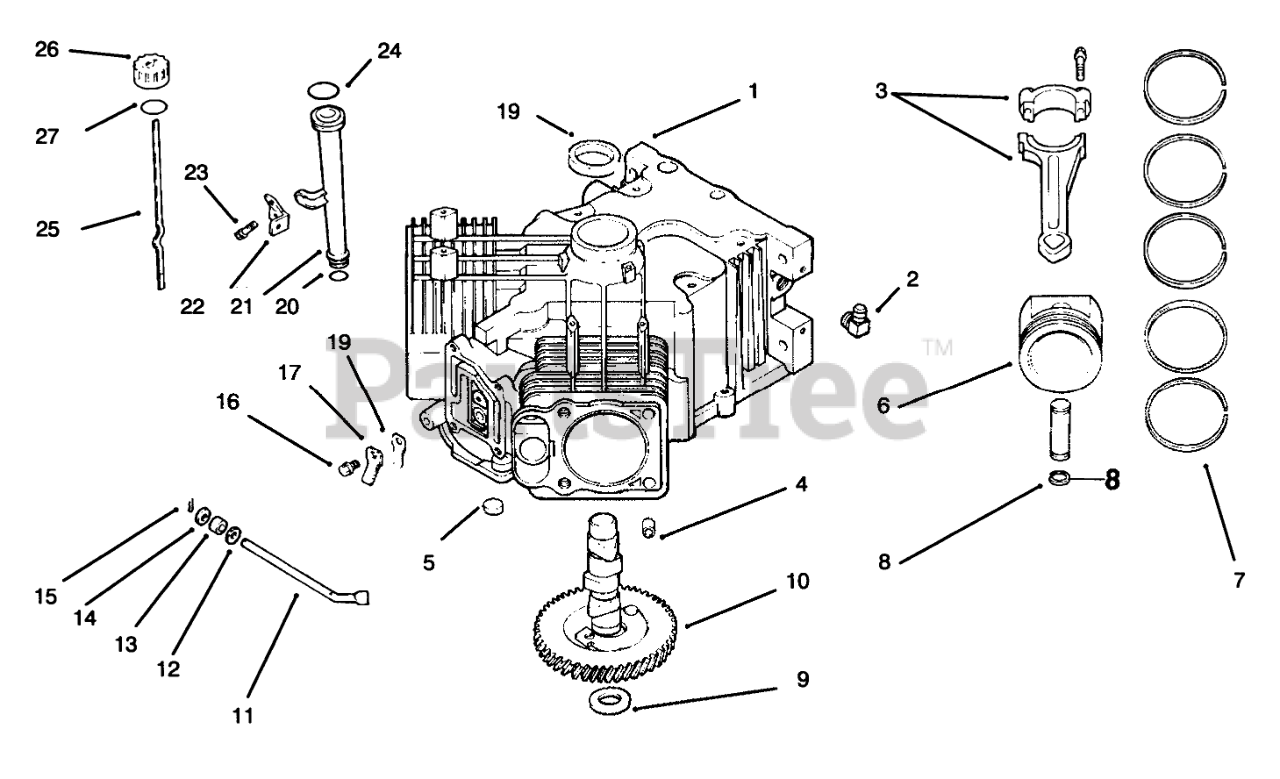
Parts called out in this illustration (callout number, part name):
1	Miniblock
2	Fitting
3	Rod-Connecting (Std.)
4	Pin-Dowel
5	Plug
6	Set-Piston w/Ring (Incl. Ref. #7-8)
7	Set-Ring (Std)
8	Retainer-Piston Pin
9	Shim-Camshaft (Green)
10	Camshaft
11	Shaft-Governor Cross
12	Washer
13	Seal-Cross Shaft
14	Washer
15	Pin-Hitch
17	Retainer-Reed
18	Beed-Breather
19	Seal-Oil
20	"O"Ring
21	Tube-Oil Fill
22	Bracket-Oil Tube
24	"O"Ring
25	Dipstick Assembly (Incl. Ref. # 26-27)
26	Kit-Fill Cap (Incl. Ref. # 27)
27	"O"Ring
